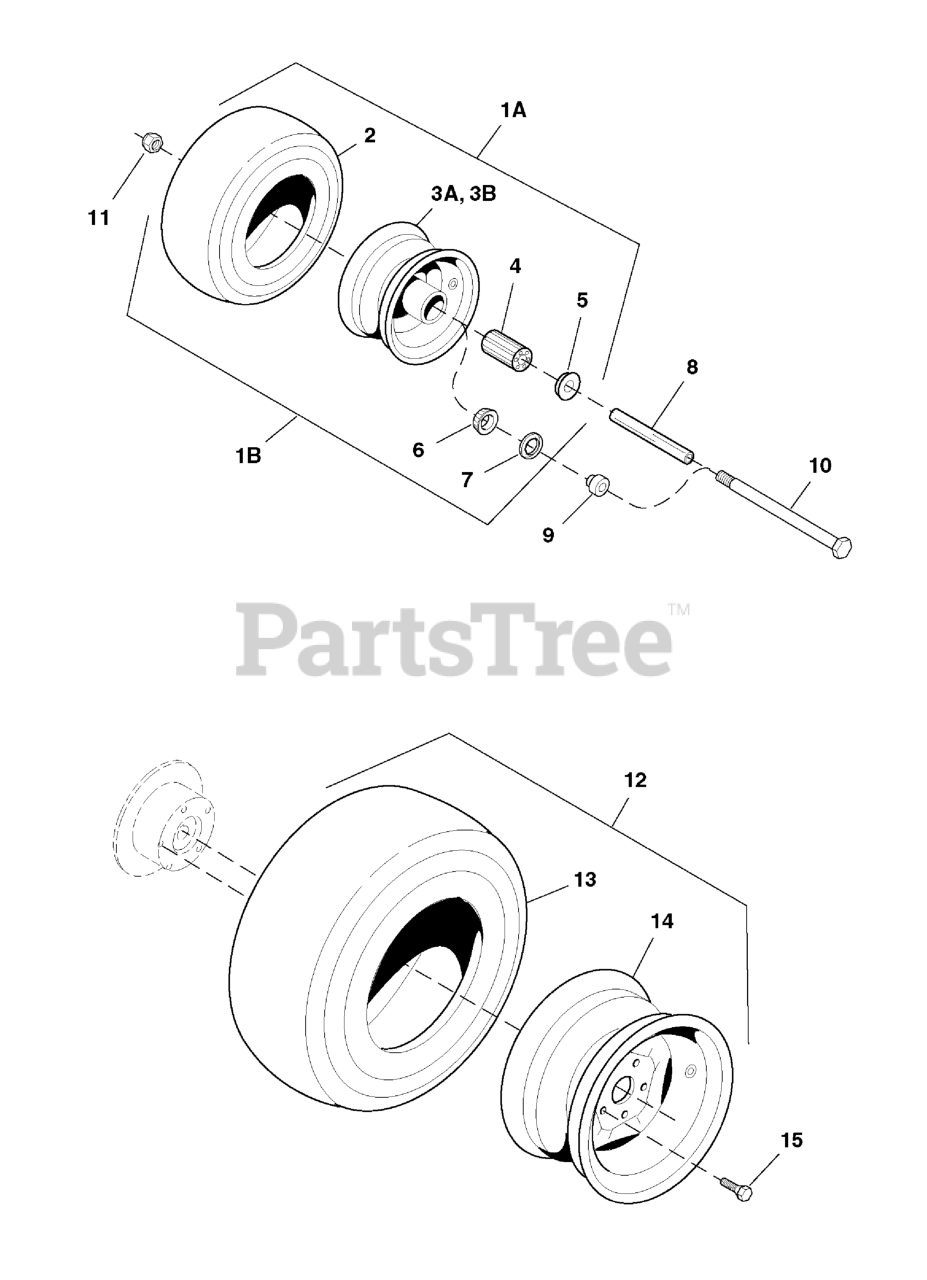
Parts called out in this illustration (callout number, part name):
1A	WHEEL & TIRE ASSEMBLY, 13 x 5.0 x 6, Complete
1B	WHEEL & TIRE ASSEMBLY, 13 x 5.0 x 6, Complete
2	TIRE, Front, 13 x 5.0 x 6
3A	WHEEL ASSEMBLY, for 13 x 5.0 x 6 Tires, Complete
3B	WHEEL ASSEMBLY, for 13 x 5.0 x 6 Tire, Complete
4	BEARING, Roller
5	RETAINER, Bearing
6	BEARING, Tapered Roller
7	SEAL, GREASE
8	SHAFT, Caster Axle
9	ADAPTER, CASTER AXLE, CZ
10	BOLT, 1/2-13 x 7-1/2
11	NUT, 1/2-13 HEX NYLON LOCK
12	WHEEL & TIRE ASSEMBLY, 23 x 10.5 x 12, Complete
13	TIRE, Rear, 23 x 10.5 x 12
14	WHEEL ASSEMBLY, for 23 x 10.5 x 12 Tires
15	WHEEL LUG, 1/2 x 1-5/8
